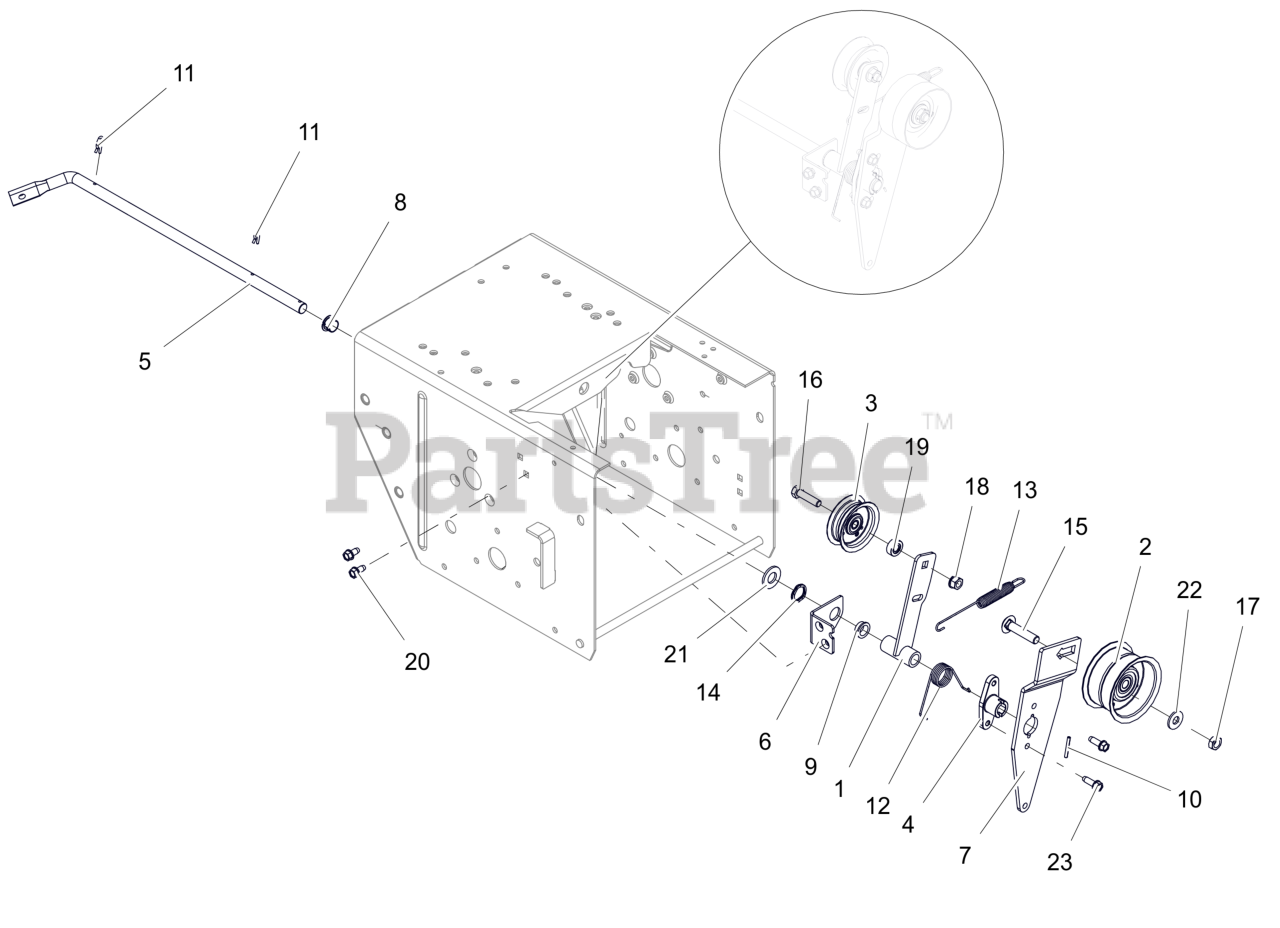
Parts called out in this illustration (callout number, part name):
1	ARM, IDLER-TRACTION
2	IDLER, FLANGE -2.75 OD X .375 ID
3	IDLER, FLAT - 2.00"
4	HUB, BRAKE ARM
5	ARM, ATTACHMENT
6	BRACKET, SUPPORT
7	ARM- IDLER-ATTACHMENT
8	BUSHING, POLYLINER-.50 SPLIT
9	BSHG,FLANGE .500X.625X.270X.75
10	PIN-ROLL .125X1.00
11	CLIP, SPRING
12	SG-TORS .067X.88
13	SG-TENS .06X.482X5.35
14	WAVE SPRING .600X.875X.25FH
15	BLT, RHSSN .38-16X1.75 G5 ZCC
16	BLT, HEX .31-18X1.25 G5 ZCC
17	NUT-LK-CTR-JAM .375-16 GB ZCC
18	NUT-LK-TOP-FLG .312-18 GF ZCC
19	SPCR, BRG .315X.500X.358X.281
20	SCR-TAP .25-20X.50 HWH ZCC
21	WSHR,FLT .531X1.062X.095 ZCC
22	WSHR,FLT .375X.875X.083 ZCC
23	SCR,TAP .25-20X.75 HWH TR ZCC
